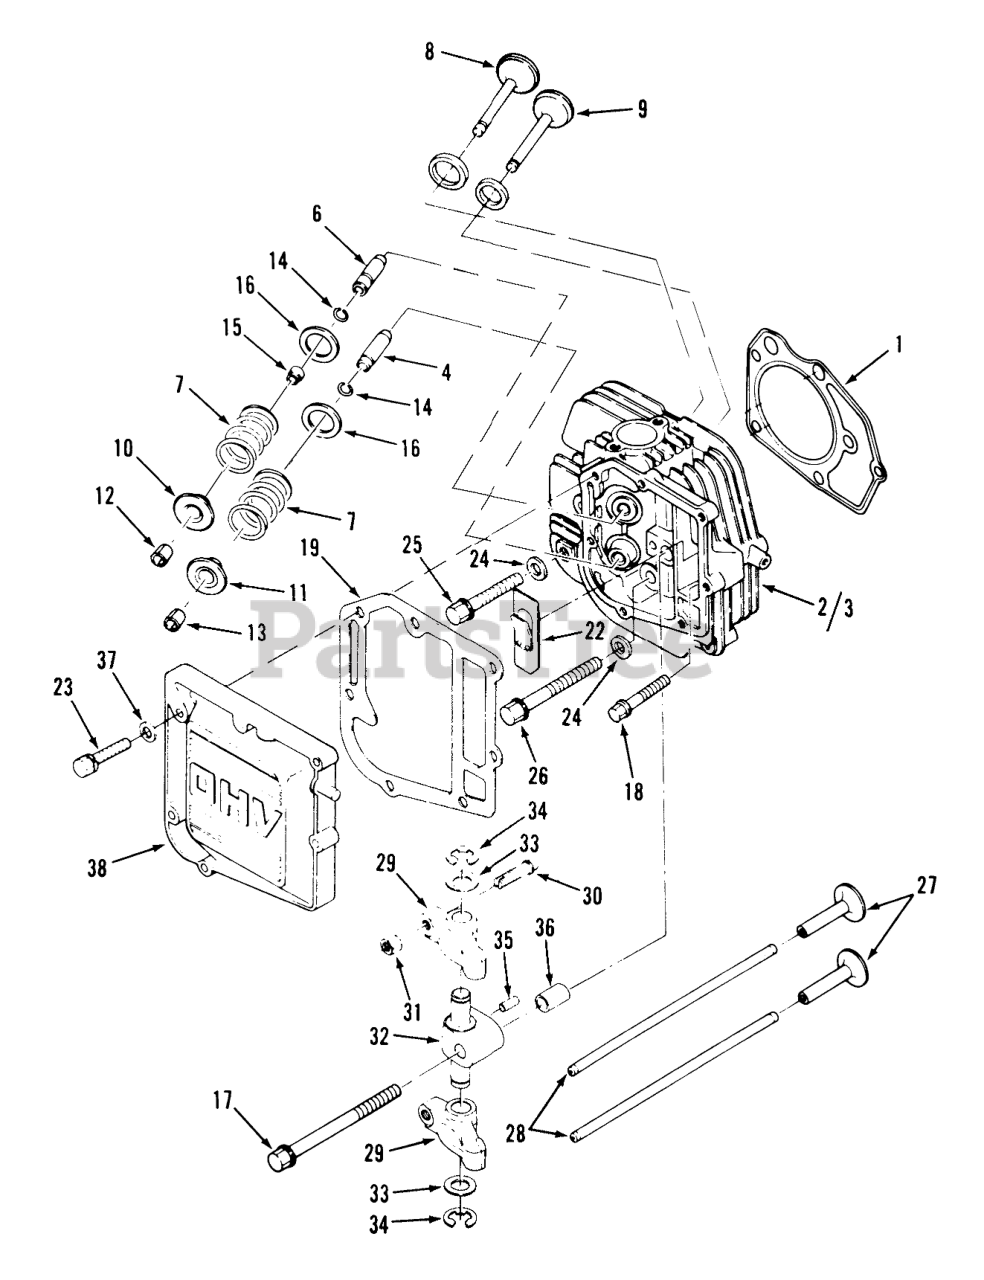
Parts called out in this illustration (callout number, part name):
1	GSKT-CYL HEAD
2	Cylinder Head Assembly W/Valves (Incl. Ref. #3-16)
3	Cylinder Head Assembly W/Out Valves (Incl. Ref. #4 & 6)
4	GUIDE-VALVE EXHAUST
6	GUIDE-VALVE INTAKE
7	SPRING-VALVE
8	VALVE-INTAKE MKD IN
9	VALVE-EXHAUST MKD EX
10	RETAINER-VLV SPG IN
11	RETAINER-VLV SPG EX
12	Lock-Intake
13	LOCK-VALVE EXHAUST
14	RING-VALVE GUIDE
15	Seal-Intake
16	WASHER-VALVE SPRING
17	BLT-CYL HD M10X125MM
18	BLT-CYL HD M8X50MM
19	Seal
22	BREATHER
23	SCRW-CP SH M6X25MM
24	WASHER-FLAT M10
25	BLT-CYL HD M10X66MM
26	BLT-CYL HD M10X86MM
27	TAPPET
28	Push Rod (Incl. Ref. #30 & 31)
29	ARM-ASS'Y-ROCKER
30	SCRW-LASH ADJUSTING
31	NUT-LASH ADJUSTING
32	SHAFT-ROCKER ARM
33	Rocker Arm Washer
34	CLIP-RETAINER
35	PIN-DOWEL
36	PIN-DOWEL HOLLOW
37	Washer
38	Valve Cover
